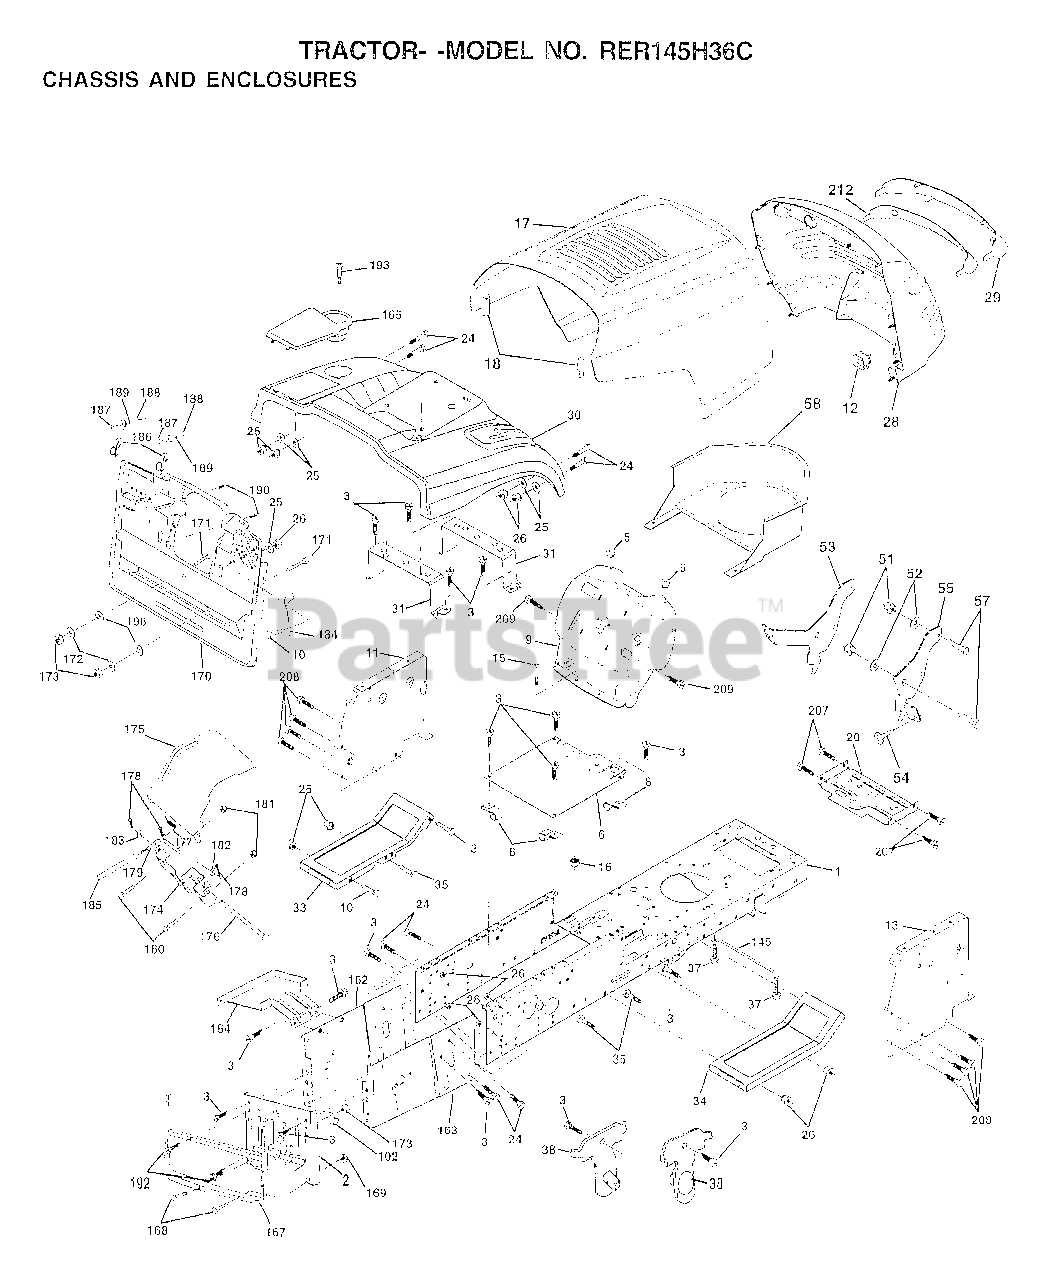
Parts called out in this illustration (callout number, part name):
2	DRAWBAR.CRD
3	SCREW
5	BUMPER-HOOD/DASH
6	SADDLE
8	"CLIP,INSULATOR"
9	DASH
11	"PANEL-DASH,LH"
12	CLIP.TINNERMAN
15	SCREW
17	HOOD.STEEL.ASSY
20	"PLATE-MTG,BATT/FU"
24	BOLT
25	WASHER
26	NUT
28	GRILL.BLK
29	LENS.GRILLE.PRIVATE LABEL
31	BRKT.SUPT.FENDER.CRD
33	FOOTREST LH
34	FOOTREST RH
35	BOLT
37	SCREW LT
38	BRKT ASM PIVOT MOWER REAR
51	NUT
52	WASHER
53	BRACKET.GRILLE.LH
54	SCREW.HEX.WS.HD
55	BRACKET.GRILLE.RH
58	DUCT.AIR.B&S.18HP
102	CLIP T
145	"ROD POVOT,CHASSIS"
162	BRKT.EXT.CHASSIS.LH.CRD
163	BRKT.EXT.CHASSIS.RH.CRD
164	SUPPORT.BATTERY.CRD
165	COVER.BATTERY.CRD.BLACK.LT
167	SUPT.ASM.BACKPLATE
168	BOLT-RD HD SQ NK
170	COVER.BACKPLATE.BLACK
171	BOLT.HEX.3/8-16X2-1/2
173	NUT
174	BRKT.SWITCH.FBI.CRD
175	GRUARD.DOOR.REAR.CRD
176	HINGE PIN
177	SPRING.COVER.LH
179	ROD.PIVOT.FBI.CRD
182	WASHER.385X.625
183	WASHER
184	BRKT.ACTUATOR.BAG.CRD
185	TUBE.LEVER.SWCH.FBI.CRD
186	LATCH ASSY.BAGGER
187	WELDNUT
188	WASHER #10
189	LOCKWASHER
190	SCREW
192	SCREW LT
193	SCREW
198	NUT PUSH
207	SCREW
208	SCREW
209	SCREW
212	INSERT LENS REFLECT
